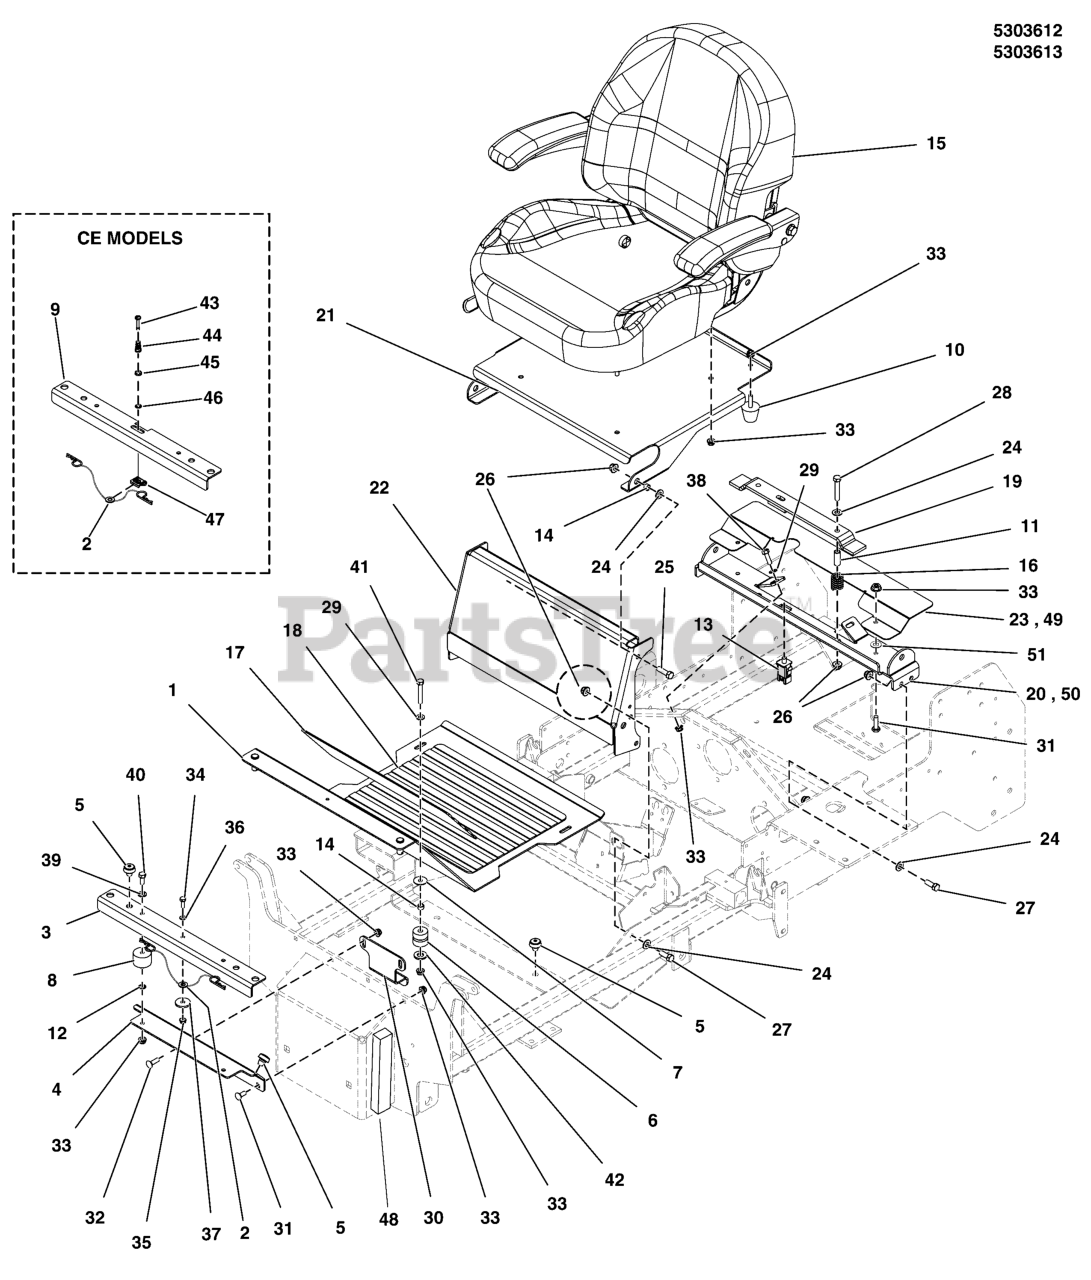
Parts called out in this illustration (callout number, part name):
1	WELD, FLOOR PLATE, IS2500, CE - RED
2	HAIRPIN COTTER LANYARD ASM, 8"
3	PLATE, FLOOR MOUNTING, TOP, DOM - RED
4	PLATE, FLOOR MOUNTING, BOTTOM - RED
5	MNT, VBRTN, RBBR
6	MOUNT, ISO,BOT,RAD 5000Z-DIESEL
7	WASHER, 5/16 FENDER
8	MOUNT,ISO,TOP,RAD 5000Z-DIESEL
9	PLATE, FLOOR MOUNTING, TOP, CE - RED
10	BUMPER, RUBBER 5/16-18
11	SPACER, .38 X .50 X 1.25, CZ
12	WASHER, 5/16 INT. TOOTH LOCK
13	SWITCH, PLUNGER, NO/NO SNAP-IN
14	SPACER, .38 X .50 X .27, CZ
15	SEAT, 2012
16	SPRING COMP .76IDX1.3LGX.105WIRE BLACK
17	SAFETY WALK, FLOOR REST, 17.13 X 6.00
18	SAFETY WALK, 11.50 X 15.00
19	WELD, SEAT SWITCH, IS2500Z -RED
20	WELD, SEAT SUPPORT - RED
21	PLATE, SEAT SUPPORT IS2500Z - RED
22	SEAT SUPPORT - RED
23	GUARD, HYDRO BELT, IS2500 - RED
24	WASHER, 3/8 SAE
25	SCREW HEX HD 3/8-16X1.250 .141TH HD G5
26	NUT, 3/8-16 HEX NYLOCK FLANGE
27	BOLT, 3/8-16 X 1" GD5 CZ
28	BOLT, 3/8-16 X 2, GD5, CZ
29	WASHER, 5/16" SAE
30	RETAINER, BATTERY - RED
31	BOLT, 5/16-18 X 3/4, CARRIAGE
32	CARRIAGE BOLT 5/16-18 X 1"
33	NUT, 5/16-18 HEX NYLOCK FLANGE
34	BOLT, 1/4-20 X 3/4 GD5 YZ
35	NUT, 1/4-20 HEX NYLOCK FLANGE
36	WASHER, 1/4 SAE
37	WASHER, .34 X 1.25 X 10 GA
38	BOLT, 5/16-18 X 1 GD5 YZ
39	WASHER, 5/16 LOCK CZ
40	BOLT, 5/16-18 X 5/8 GD5 YZ
41	BOLT, 5/16-18 X 2, GD5
42	WASHER, 1/2 GD9 YZ
43	DZUS, 1/4 TURN FASTENER, D8Z29MM
44	DZUS, EJECTOR SPRING
45	DZUS, CUPPED WASHER
46	DZUS, RECEPTACLE, CLIP-ON, D8
47	DZUS, RETAINER PUSH-ON, SS
48	FOAM, 1/2 X 1 X 8.50 LONG
48	PAD, RUBBER MOUNT
49	GUARD, HYDRO BELT - RED
50	SUPPORT, SEAT - RED
51	5/16 PUSH-ON NUT RETAINER, STL, CZ
